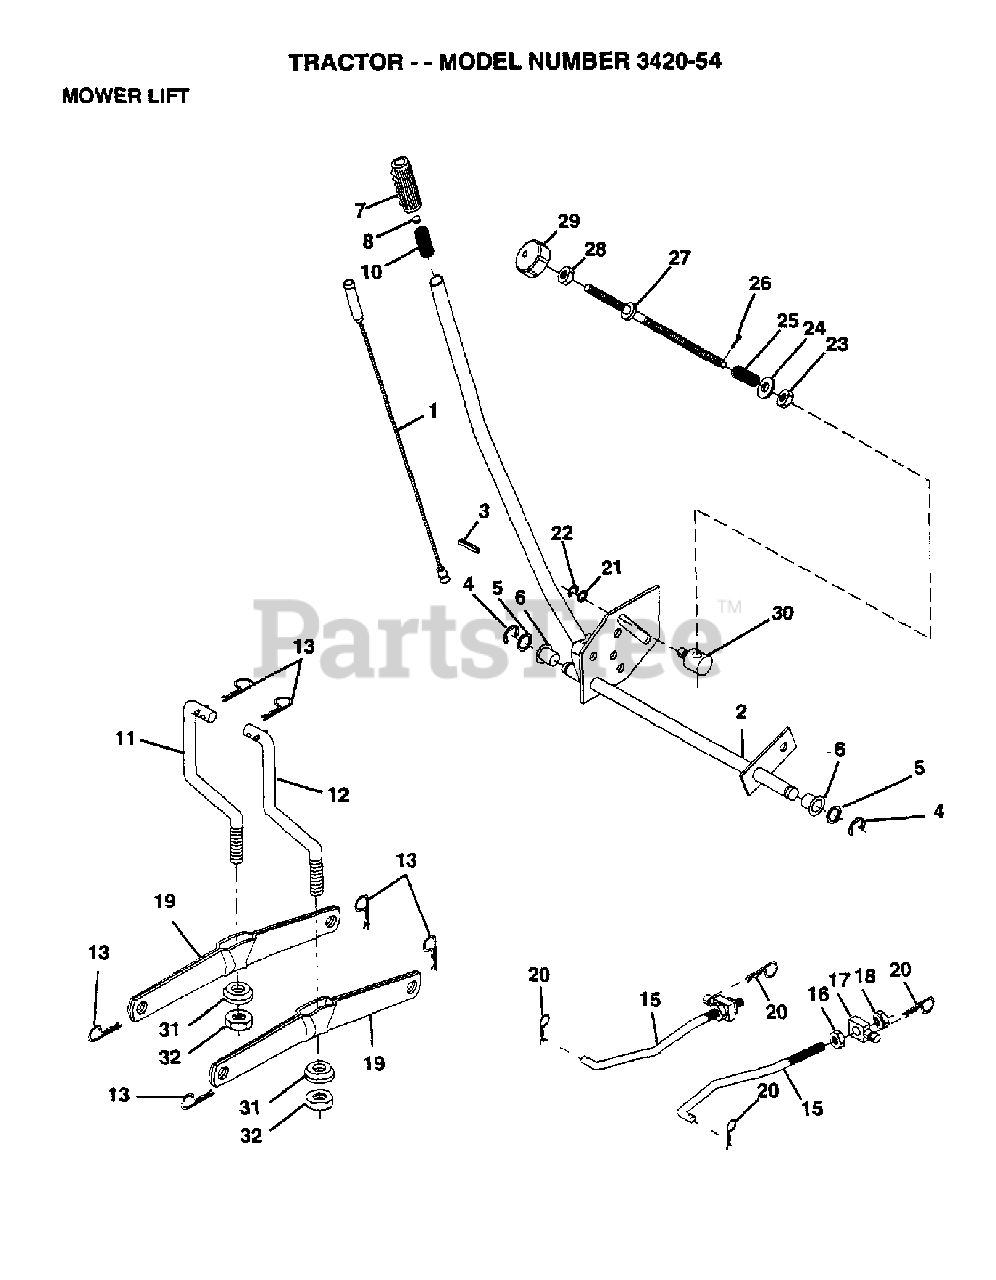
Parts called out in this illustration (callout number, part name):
1	WIRE.INNER.HANDLE.LIFT.LEVER
3	PIN GROOVE
4	RETAINING RING LT
6	BEARING.NYLON
7	GRIP
8	PLUNGER BUT KIT
10	SPRING, COMP T
11	LINK LIFT LH
12	Lift Link Assembly, RH
13	RETAINER SPRING
15	FRONT LINK
16	NUT.HEX.JAM.1/2-13
18	NUT.LK.W/WSH.1/2.
19	ARM.REAR.SUSPENSION
20	Poulan TBD
21	WASHER
22	KLIP RING
24	WASHER
25	SPRING.COMP.INF.H
27	ROD.LIFT.ADJUSTABLE
28	NUT
29	KNOB INF 3/8-16
30	TRUNION LT
32	NUT CROWNLOCK 3/8-24
